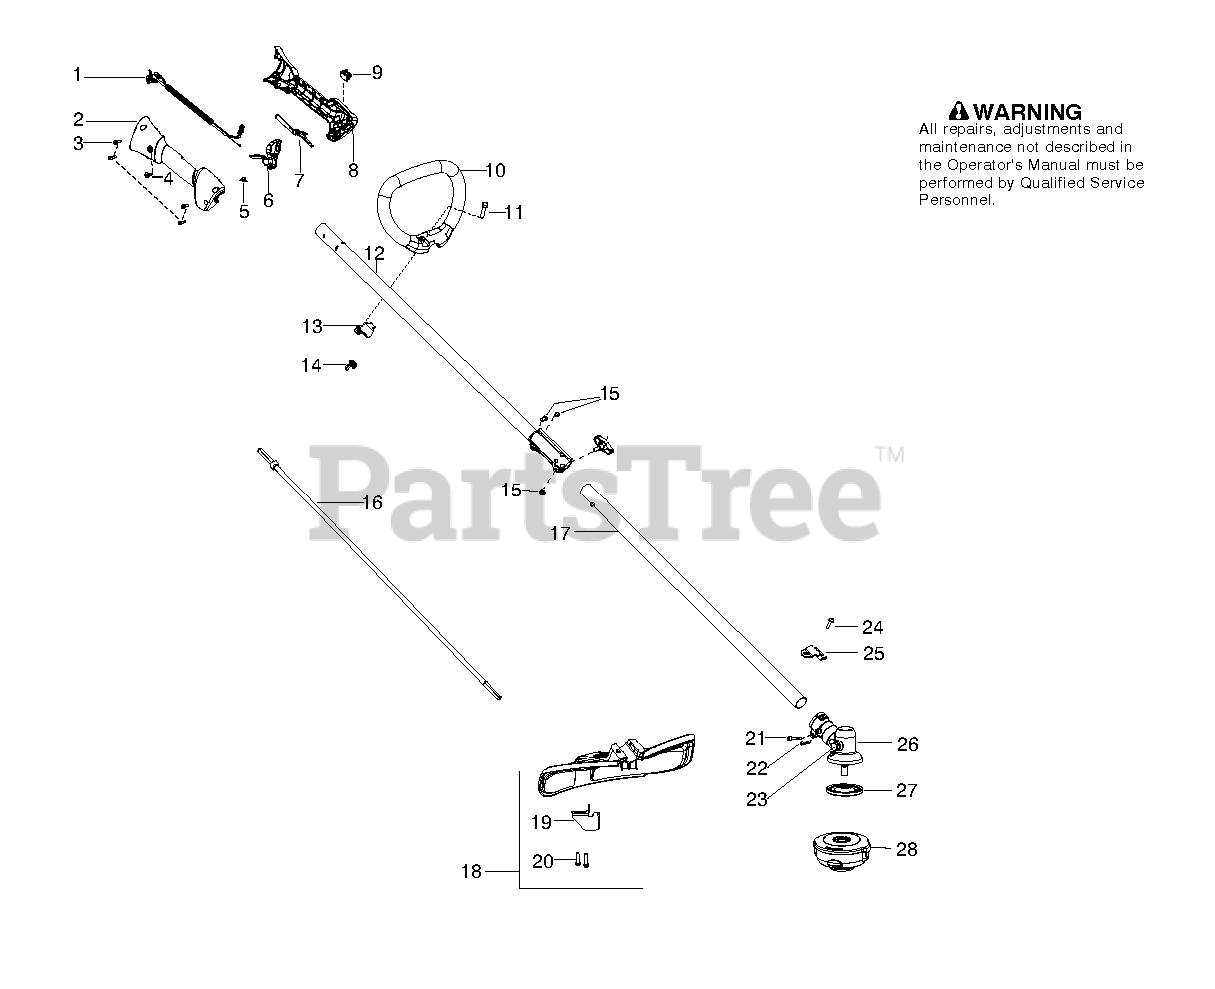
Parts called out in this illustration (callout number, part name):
1	ASSY CABLE / WIRE HARNESS
2	HSG THROTTLE RIGHT HVA
3	SCREW M4 X 1.75 PT 16MM
4	SCREW-10-14 X 1/2 PLASTITE
5	SPRING TRIGGER
6	TRIGGER THROTTLE HVA ORANGE
7	THROTTLE LOCKOUT HVA ORANGE
8	HSG THROTTLE LEFT HVA
9	SWITCH
11	BOLT, TYPE 2
12	KIT UPPER SHAFT SILVER
13	CLAMP ASSIST HANDLE
14	WINGNUT, TYPE 2
15	ASSY COUPLER BLACK
17	KIT LOWER SHAFT
18	KIT COBI SHIELD
19	Limiter - Line
21	SCREW - CARB. ADAPTOR
23	PLUG GREASE 9MM
24	SCREW 1/4-20 X 7/8 (TAP
25	BRACKET SHIELD STRAIGHT SHAFT
26	ASSY GEARBOX
27	DRIVE DISC
28	T25 TRIM HEAD 10MM LH
